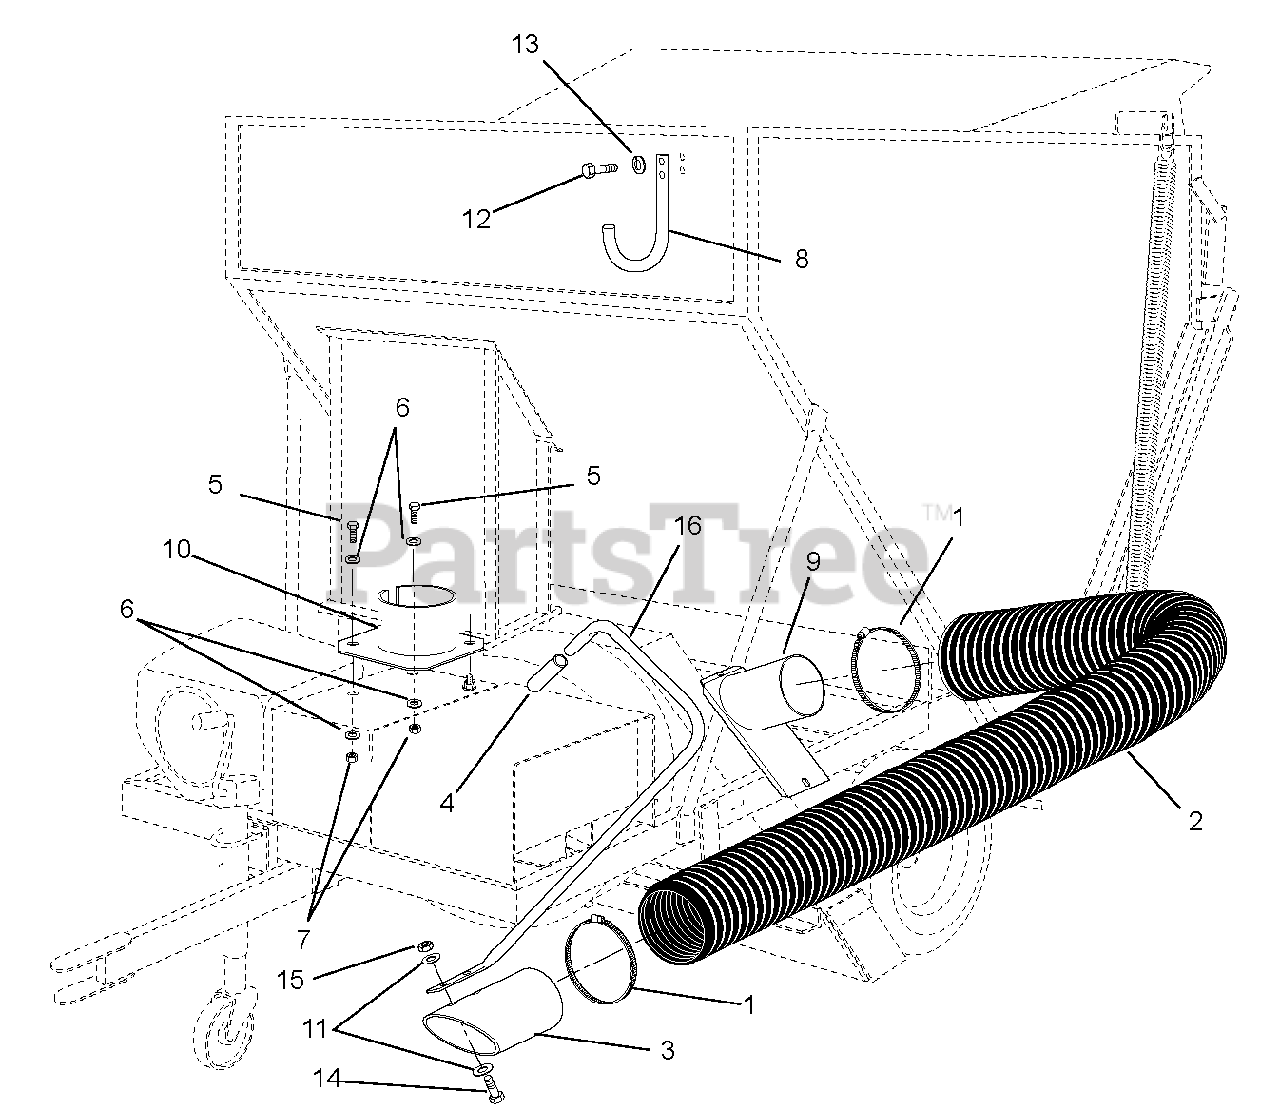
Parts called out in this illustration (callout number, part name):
1	Clamp, Hose
2	Hose, 6-in. x 10 ft.
3	Tube, Nozzle
4	Grip, Hand
5	Cap Screw, Hex Head .375-16 x 1
6	Washer, Flat .375
7	Nut, Nyloc Hex .375-16
8	Hanger, Flex Hose
9	Weldment, Adapter Tube
10	Holder, Nozzle
11	Washer, Flat .312
12	Cap Screw, Hex Head .375-16 x 2
13	Washer, Lock .375
14	Cap Screw, Hex Head .312-18 x 1
15	Nut, Hex Flange Lock .312-18
16	Handle, Nozzle
